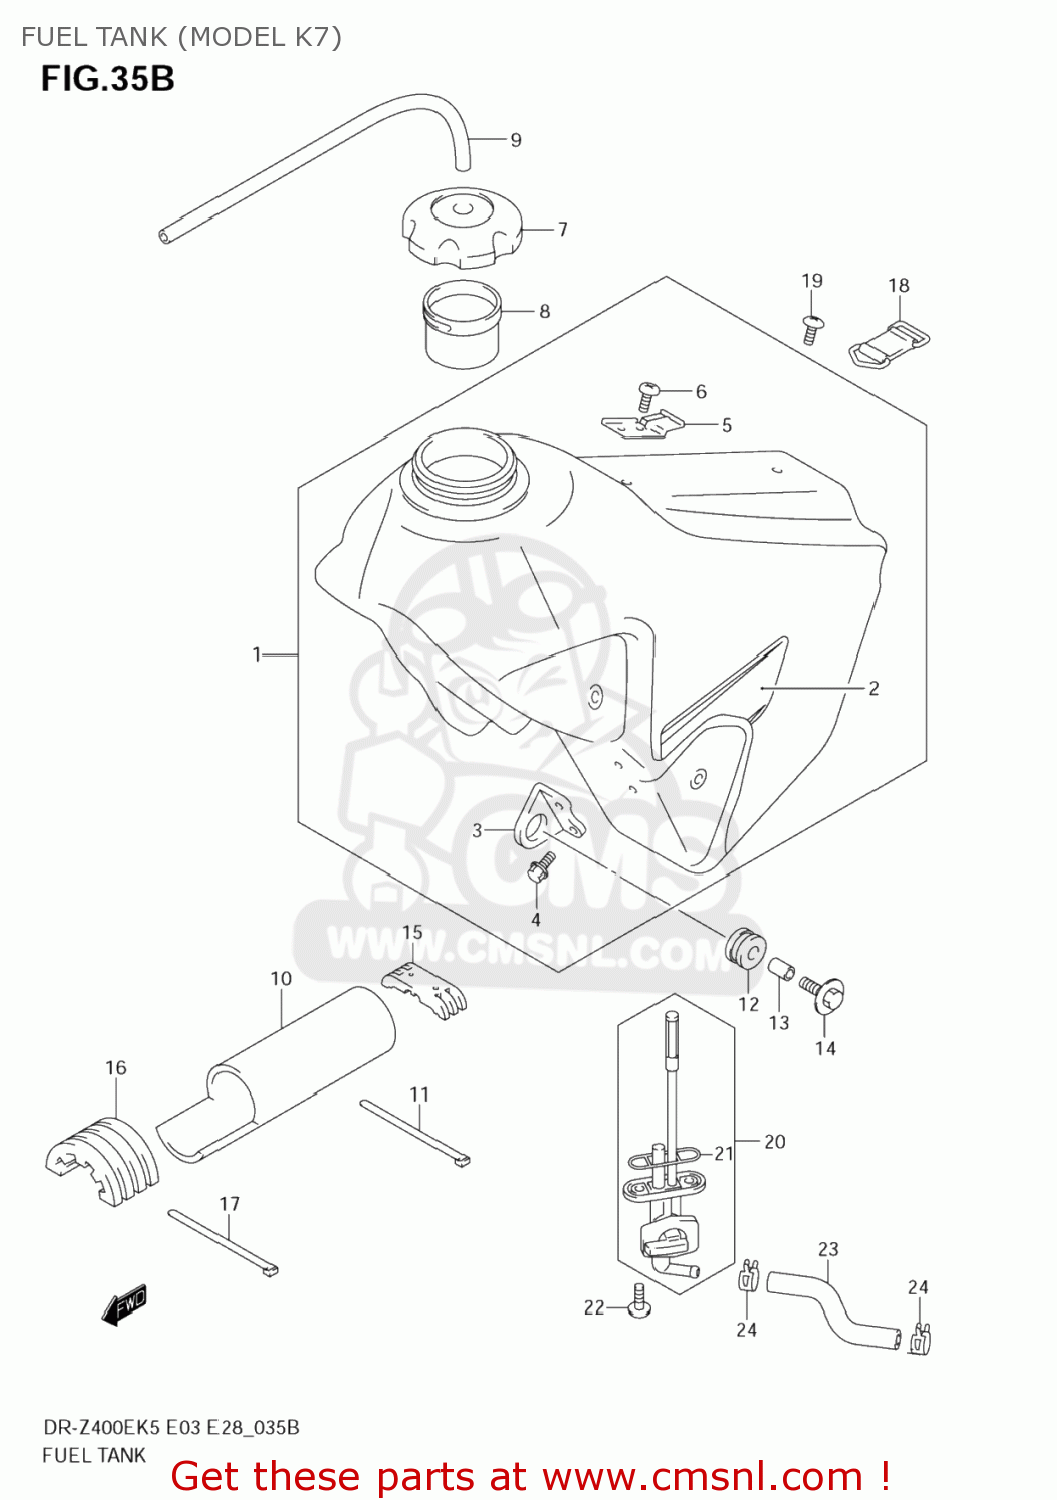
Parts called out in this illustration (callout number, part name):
1	TANK ASSY,FUEL(YELLOW)
2	TAPE SET,FUEL TANK
3	BRACKET,FUEL TANK FR
4	BOLT
5	HOOK,SEAT FR
6	SCREW
7	CAP ASSY,FUEL TANK FILLER
8	TUBE,FILLER INLET
9	HOSE(5X8.2X600)
10	SHIELD,FUEL TANK
11	CLAMP(L:300)
12	CUSHION,MUFFLER
13	SPACER(6.5X9X13.5)
14	BOLT(6X30)
15	CUSHION,FUEL TANK RR
16	CUSHION,FUEL TANK
17	CLAMP(L:300)
18	BAND,FUEL TANK RR
19	SCREW
20	COCK ASSY,FUEL
21	GASKET,JOINT (NAS)
22	BOLT
23	HOSE,FUEL
24	CLIP
